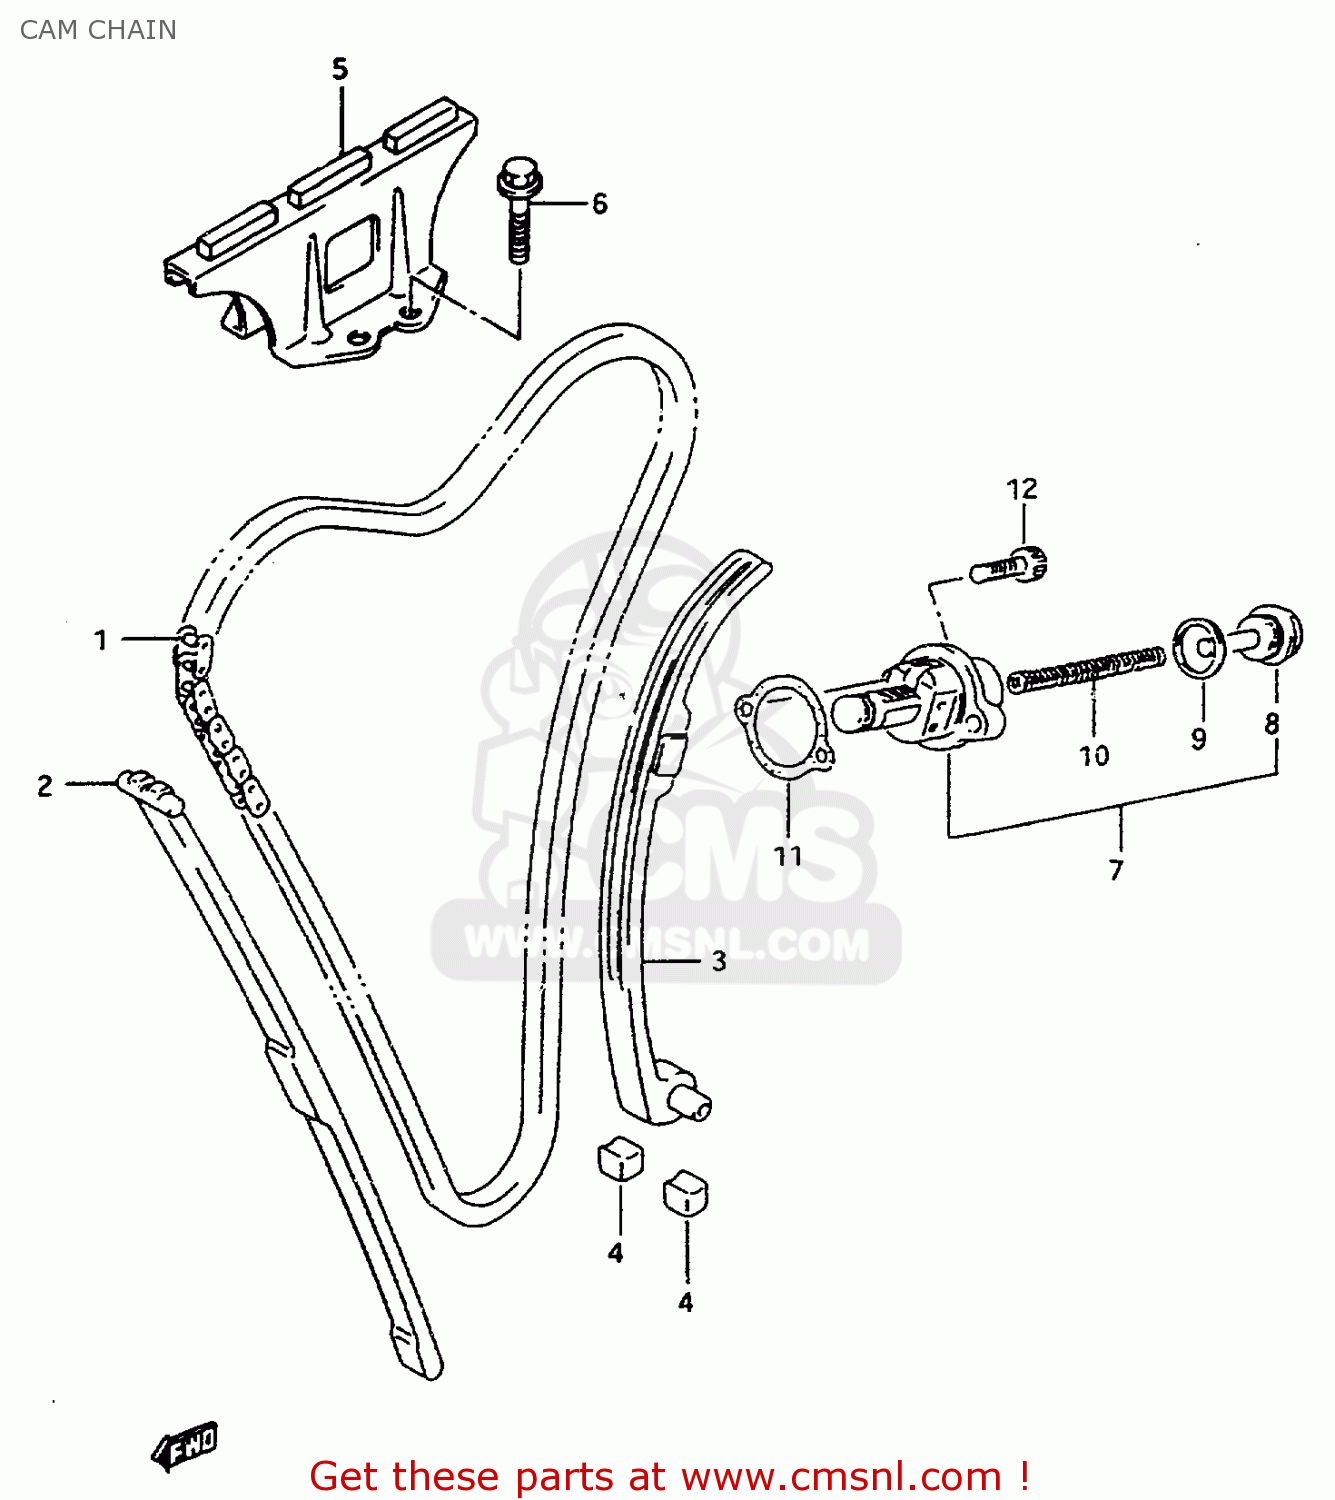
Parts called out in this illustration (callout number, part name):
1	CHAIN,CAMSHAFT DRIVE
2	GUIDE,CAM CHAIN NO.1
3	TENSIONER,CAM CHAIN
4	CUSHION,CAM CHAIN TENSIONER
5	GUIDE,CAM CHAIN NO.2
6	BOLT
7	ADJUSTER ASSY,TENSIONER
8	PLUG
9	GASKET (NAS)
10	SPRING
11	GASKET,TENSIONER ADJUSTER (NAS)
12	BOLT,CL.COVER
